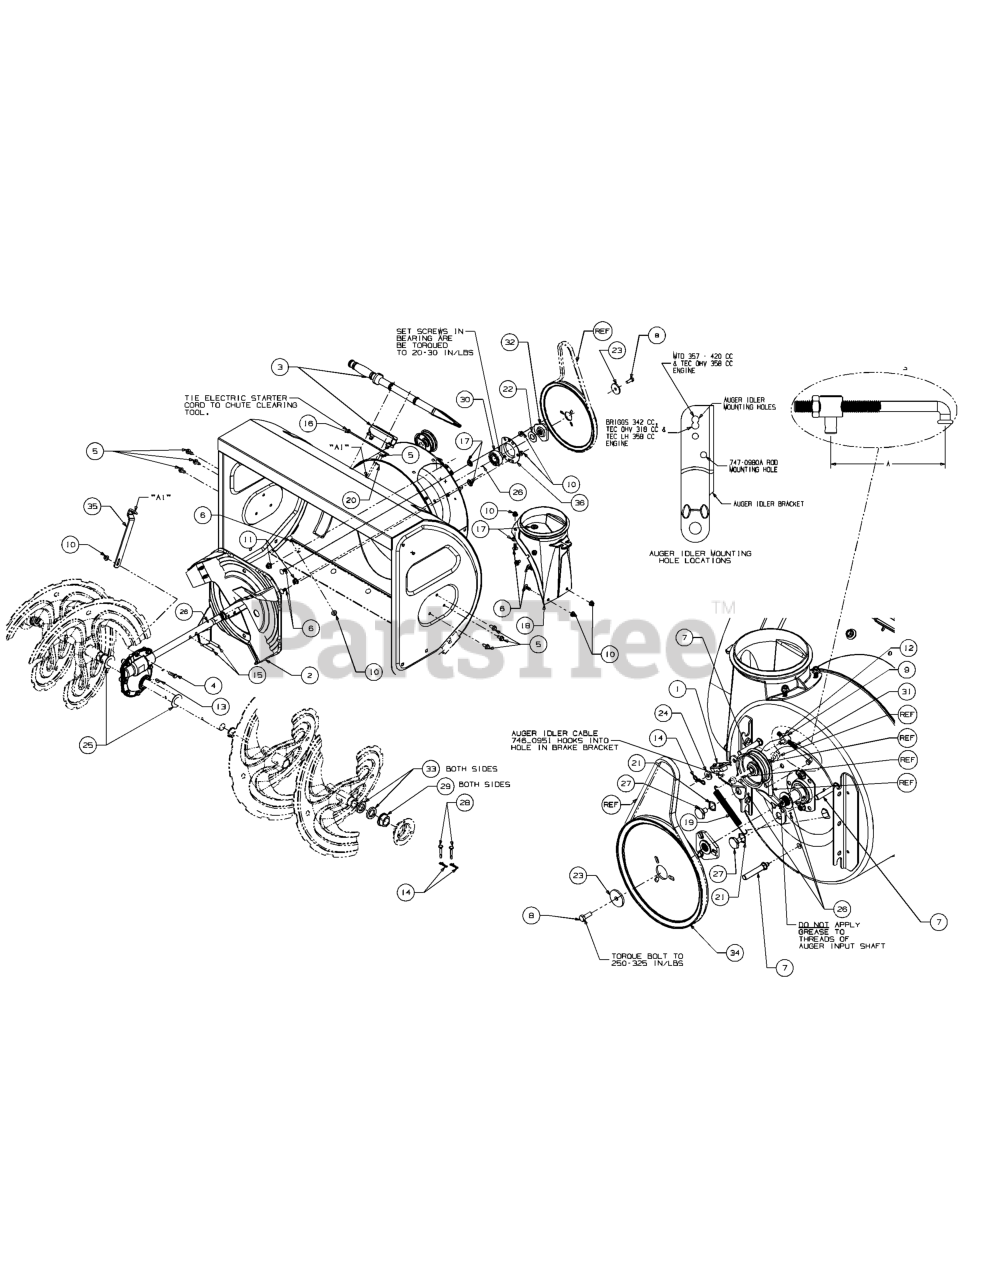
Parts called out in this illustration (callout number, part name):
1	Bracket Assy-Br
2	Impeller Asm-16"
3	Tool-Cleanout
3	Clip-Tool Mtg
4	Screw-Hex Cap 5
6	Carriage Bolt 5/16-18 X .75
7	Screw-5/16-18 Tt
8	Screw-Hex Cap 5/1
9	Engagement Ferru
10	Nut-Flglk 5/16-18
11	Nut-Flange Lk.Nylo
12	Nut-Hex Jam
13	Key-Woodruff #91
14	Pin-Cotter
15	Pin-Spring Spir
16	Tie-Cable 7"
17	Nut-Push On
18	Chute Adapter
19	Spring-Extension
20	Washer-Fl
21	Washer-Wave .660 I
22	Washer-Fl-.760Id X
23	Washer-Fl
24	Washer-Fl.344
25	Washer-Flat
26	Grease
27	Screw-Shld .625
28	Shear Pin .25X150
29	Bearing-Flange
30	Bearing-Self-Al
31	Rod-Auger Idler
32	Pulley-Adapter .75
34	Pulley-Auger 10.0
36	Bearing Housing
